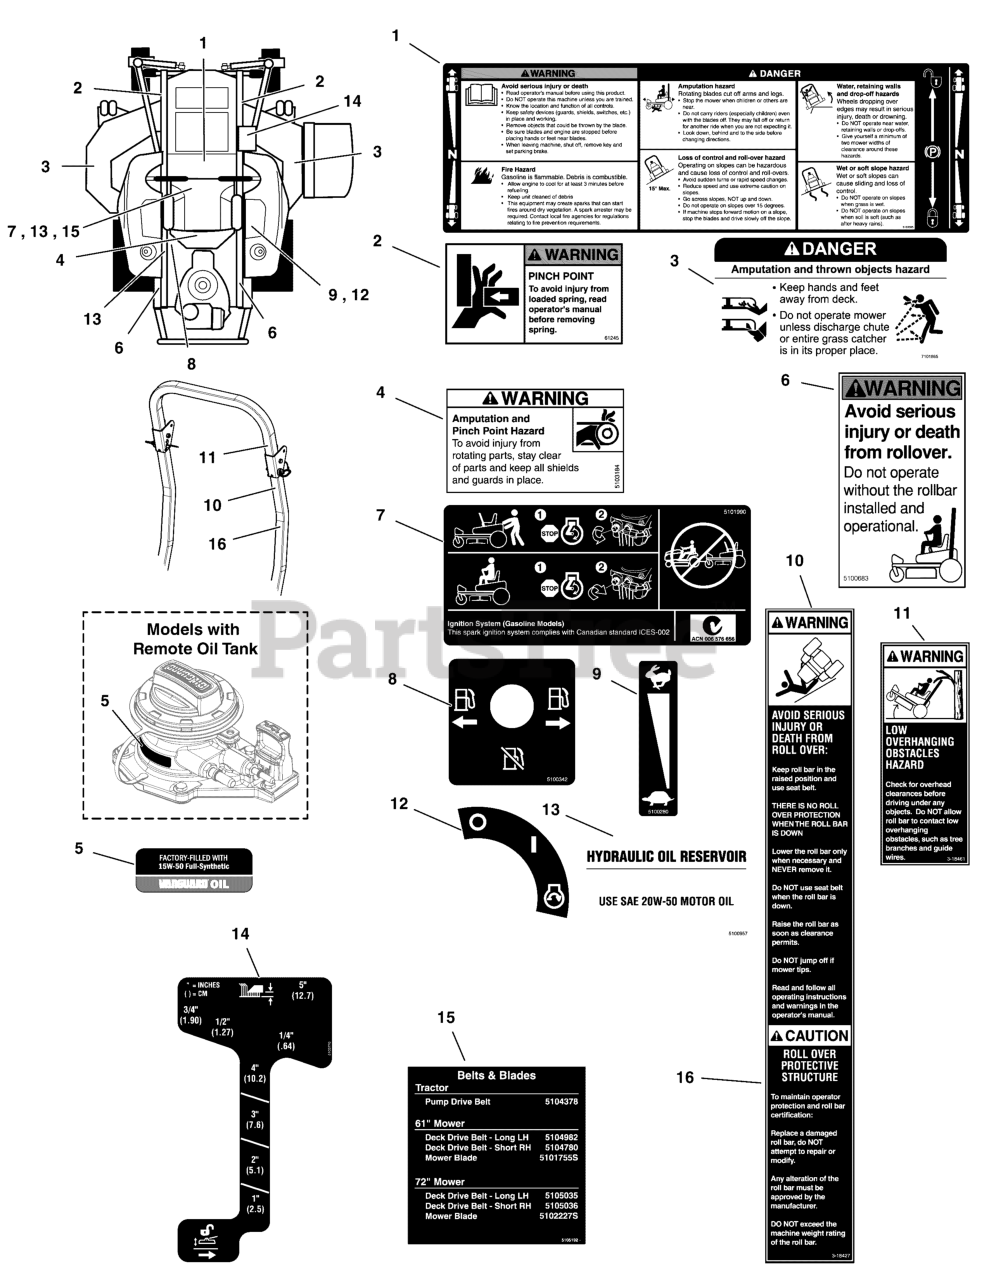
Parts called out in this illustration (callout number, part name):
1	DECAL, MAIN SAFETY
2	DECAL, Pinch Point
3	DECAL, Danger
4	DECAL, Warning
6	DECAL, WARNING, ROLL BAR
7	DECAL, TRANSAXLE RELEASE, S200XT
8	DECAL, FUEL VALVE
9	DECAL, THROTTLE CONTROL
10	DECAL, WARNING, FOLDING ROPS
11	DECAL, WARNING OVERHANG, ROPS (SV)
12	DECAL, Ignition / Throttle
13	DECAL, HYDRAULIC OIL, SAE 20W50
14	DECAL, CUT HEIGHT, IS700/ZTS700
15	DECAL, Belt & Blade
16	DECAL, CAUTION, FOLDING ROPS
